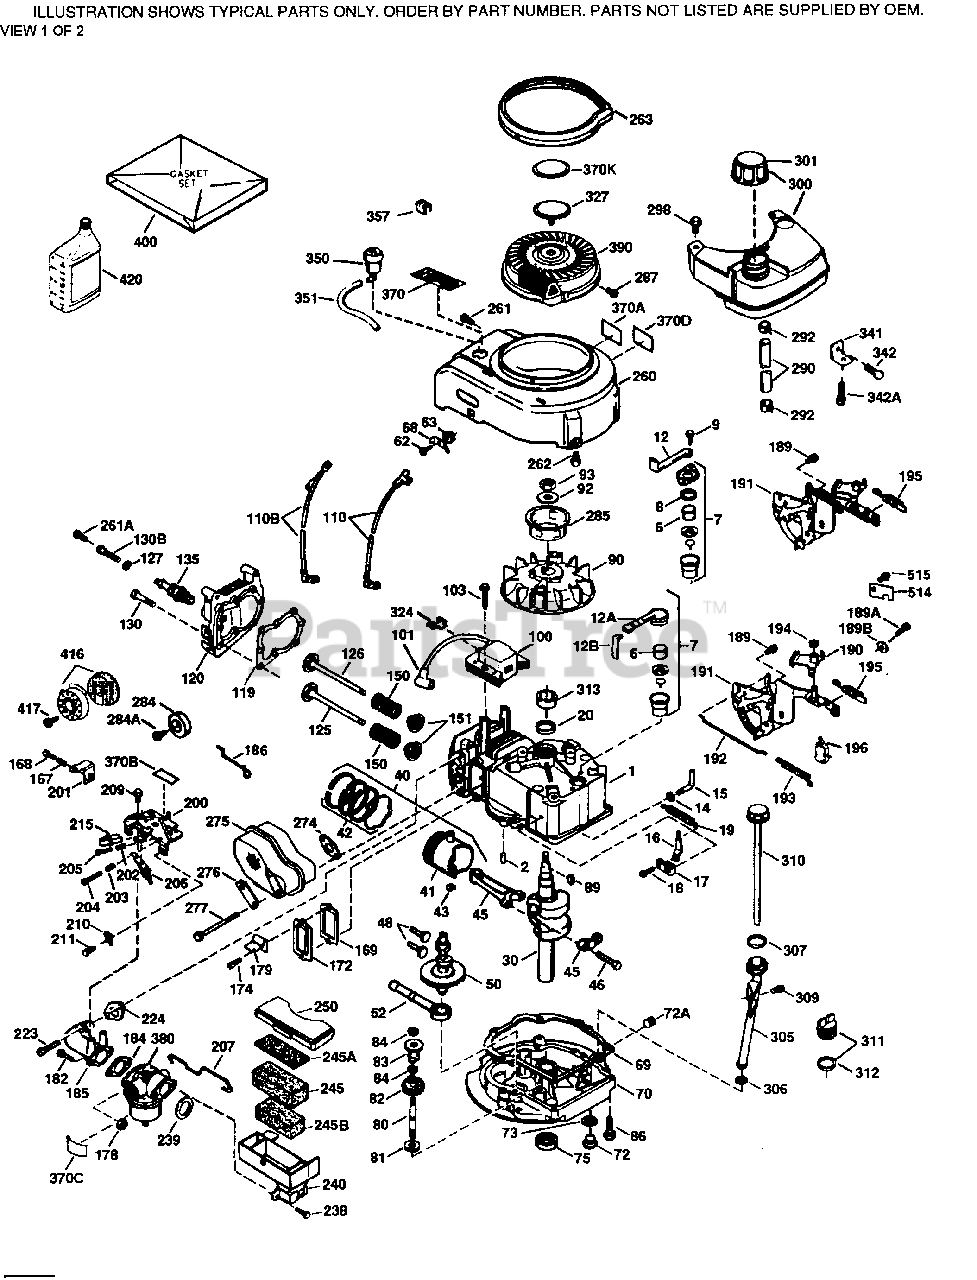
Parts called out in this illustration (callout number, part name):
1	"Cylinder (Incl. 2,7,20 & 125)
2	Dowel Pin
6	Breather Element
7	Breather Ass'y. (Incl. 6 & 12A)
12	Breather Cover & Tube (Incl. 12B)
12B	Breather Tube Elbow
14	Flat Washer
15	Governor Rod (Incl. 14)
16	Governor Lever
17	Governor Lever Clamp
18	Screw, 8-32 x 5/16"
19	Extension Spring
20	Oil Seal
30	Crankshaft
40	Piston, Pin & Ring Set (Std.)
40	Piston, Pin & Ring Set (.010" OS)
40	Piston, Pin & Ring Set (.020" OS)
41	Piston & Pin Ass'y. (Std.) (Incl. 43)
41	Piston & Pin Ass'y. (.010" OS) Incl. 43
41	Piston & Pin Ass'y. (.020" OS) Incl. 43
42	Ring Set (Std.)
42	Ring Set (.010" OS)
42	Ring Set (.020" OS)
43	Piston Pin Retaining Ring
45	Connecting Rod Ass'y. (Incl. 46)
46	Connecting Rod Bolt
48	Valve Lifter
50	Camshaft (MCR)
52	Oil Pump Ass'y.
69	Mounting Flange Gasket
70	Mounting Flange (Incl. 72 thru 83)
72	Oil Drain Plug (Incl. 73)
72A	Oil Drain Plug
73	Drain Plug Gasket
75	Oil Seal
80	Governor Shaft
82	Governor Gear Ass'y. (Incl. 81)
83	Governor Spool
86	Screw, 1/4-20 x 1-1/4"
89	Flywheel Key (also available in Packa ged Part #740007B)
90	Flywheel
92	Belleville Washer
93	Flywheel Nut
100	Solid State Ignition
101	Spark Plug Cover
103	Screw, Torx T-15, 10-24 x 15/16"
110	Ground Wire
119	* Cylinder Head Gasket
120	Cylinder Head
125	Exhaust Valve (Std.) (Incl. 151)
125	Exhaust Valve (1/32" OS) (Incl. 151)
126	Intake Valve (Std.) (Incl. 151)
126	Exhaust Valve (1/32" OS) (Incl. 151)
130	Screw, 5/16-18 x 1-1/2"
135	Resistor Spark Plug (RJ19LM) also ava ilable in Packaged Part #740081
150	Valve Spring
151	Valve Spring Cap
169	* Valve Cover Gasket
172	Valve Cover
174	Screw, 10-24 x 9/16"
178	Nut & Lock Washer 1/4-28
179	Retainer Clip
182	Screw, 1/4-28 x 7/8"
184	* Carburetor To Intake Pipe Gasket
185	Intake Pipe
186	Governor Link
189	Screw, 1/4-20 x 3/8"
191	S.E. Brake Bracket (Incl. 195)
195	Terminal
200	Control Bracket (Incl. 202 thru 205)
202	Compression Spring
203	Compression Spring
204	Screw, 5-40 x 7/16"
205	Screw, 6-32 x 21/32"
206	Terminal
207	Throttle Link
209	Screw, 10-24 x 9/16"
215	Control Knob
223	Screw, 1/4-20 x 1"
224	* Intake Pipe Gasket
238	Screw, 10-32 x 49/64"
239	* Air Cleaner Gasket
245	Air Filter (Paper) (also available in Packaged Part #740095 (Qty.2))
250	Air Filter Cover (Craftsman)
260	Blower Housing
261	Screw, 10-24 x 9/16"
262	Screw, 1/4-20 x 1/2"
275	Muffler (Incl. 277)
277	Screw, 1/4-20 x 2-5/16"
284	Muffler Deflector (Incl. 284A) Option al
284A	Screw, 8-32 x 3/8" (Optional)
285	Starter Cup
287	Screw, 8-32 x 21/64"
290	Fuel Line
292	Fuel Line Clamp
300	Fuel Tank (Incl. 292 & 301)
301	Fuel Cap
305	Oil Fill Tube
306	* "O"-Ring
307	"O" Ring
309	Screw, 10-32 x 1/2"
310	Dipstick
324	Terminal
370A	Lubrication Decal
370B	Control Decal
370K	Starter Decal this)
380	Carburetor (Incl. 184)
390	Rewind Starter NOTE: This engine cou ld have been built with 590688 starte r. Refer to the design of the air int ake louvers for part identification. Individual starter parts do not inter change.
400	* Gasket Set (Incl. items marked PK in notes). Incl. Part #'s 26756 (1), 27 234A (1), 33735 (1), 34265 (1), 34338 (1), 34690A (1), 35261 (1), 36477 (1 )
416	Spark Arrestor Kit (Incl. 416) Option al
417	Screw, 8-32 x 3/8" (Optional)
999	Summer Maintenance Kit (incl. Oil, Sp ark Plug, Air Cleaners (2), & Ultra-F resh)
